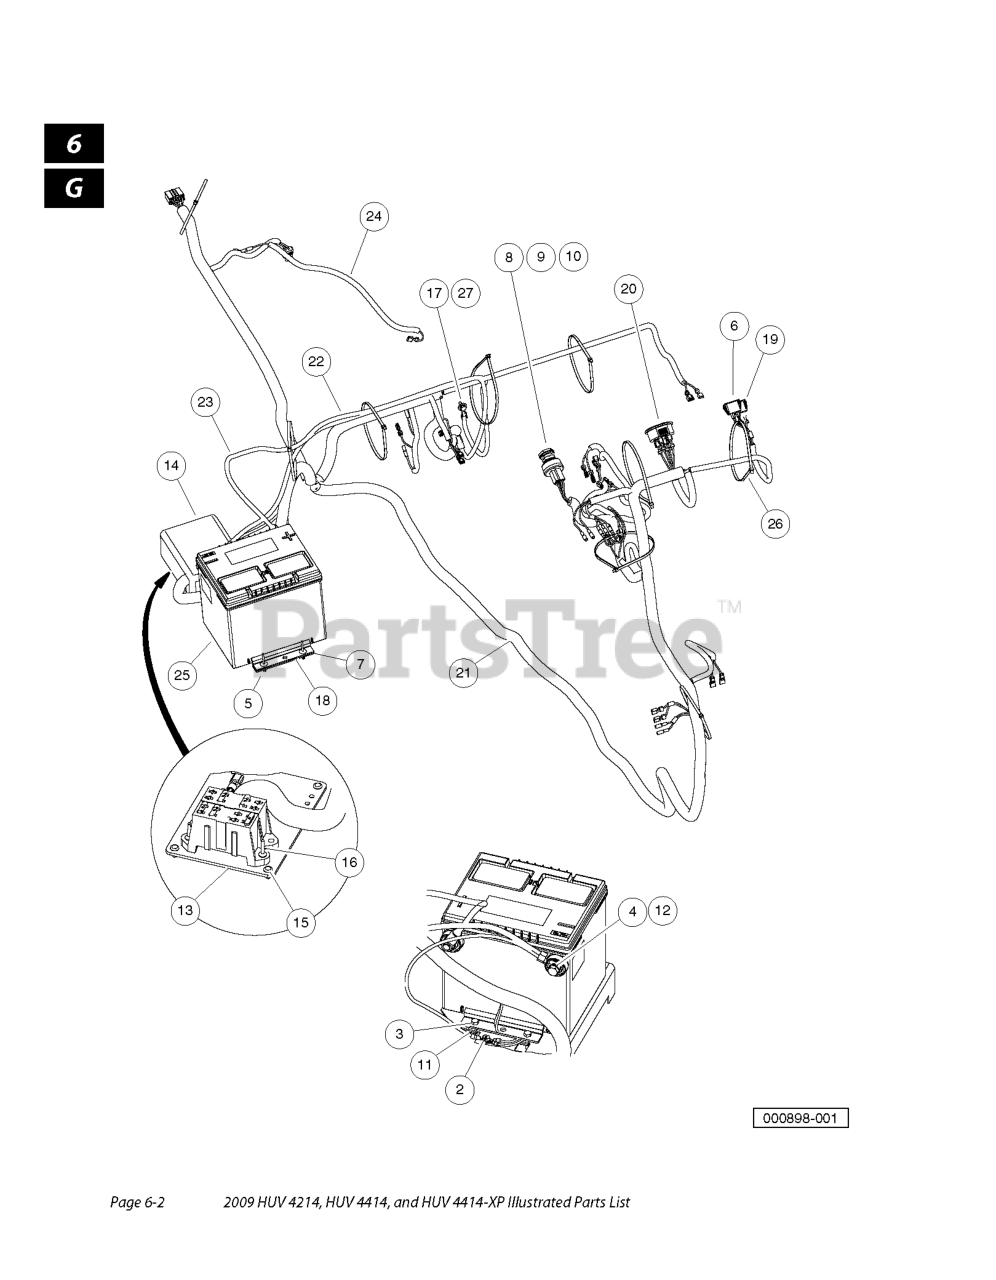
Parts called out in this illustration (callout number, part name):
2	SCREW, HEX WASH
5	RIVET, 3/16 POP
6	LIGHT, OIL
7	CLAMP - BATTERY
8	KEY SWITCH 12V KEY START
9	SPACER, KEYSWITCH
10	NUT, KEYSWITCH
11	U-NUT M6-1.0 PREV TORQUE
12	LOCKWASHER, 3/8 STAINLESS STL
13	PLATE, ELECTRICAL
14	COVER, ELECTRICAL
15	FASTENER, PUSH-IN
16	RIVET, DRIVE
17	BOLT, M6 X 1 X 16 LOCTITE
18	SPACER, BATTERY
20	GAUGE FUEL-HOUR SEP GND
25	BATTERY, START, 12V
26	TIE WRAP , 11" NYLON
27	WASHER, M6
